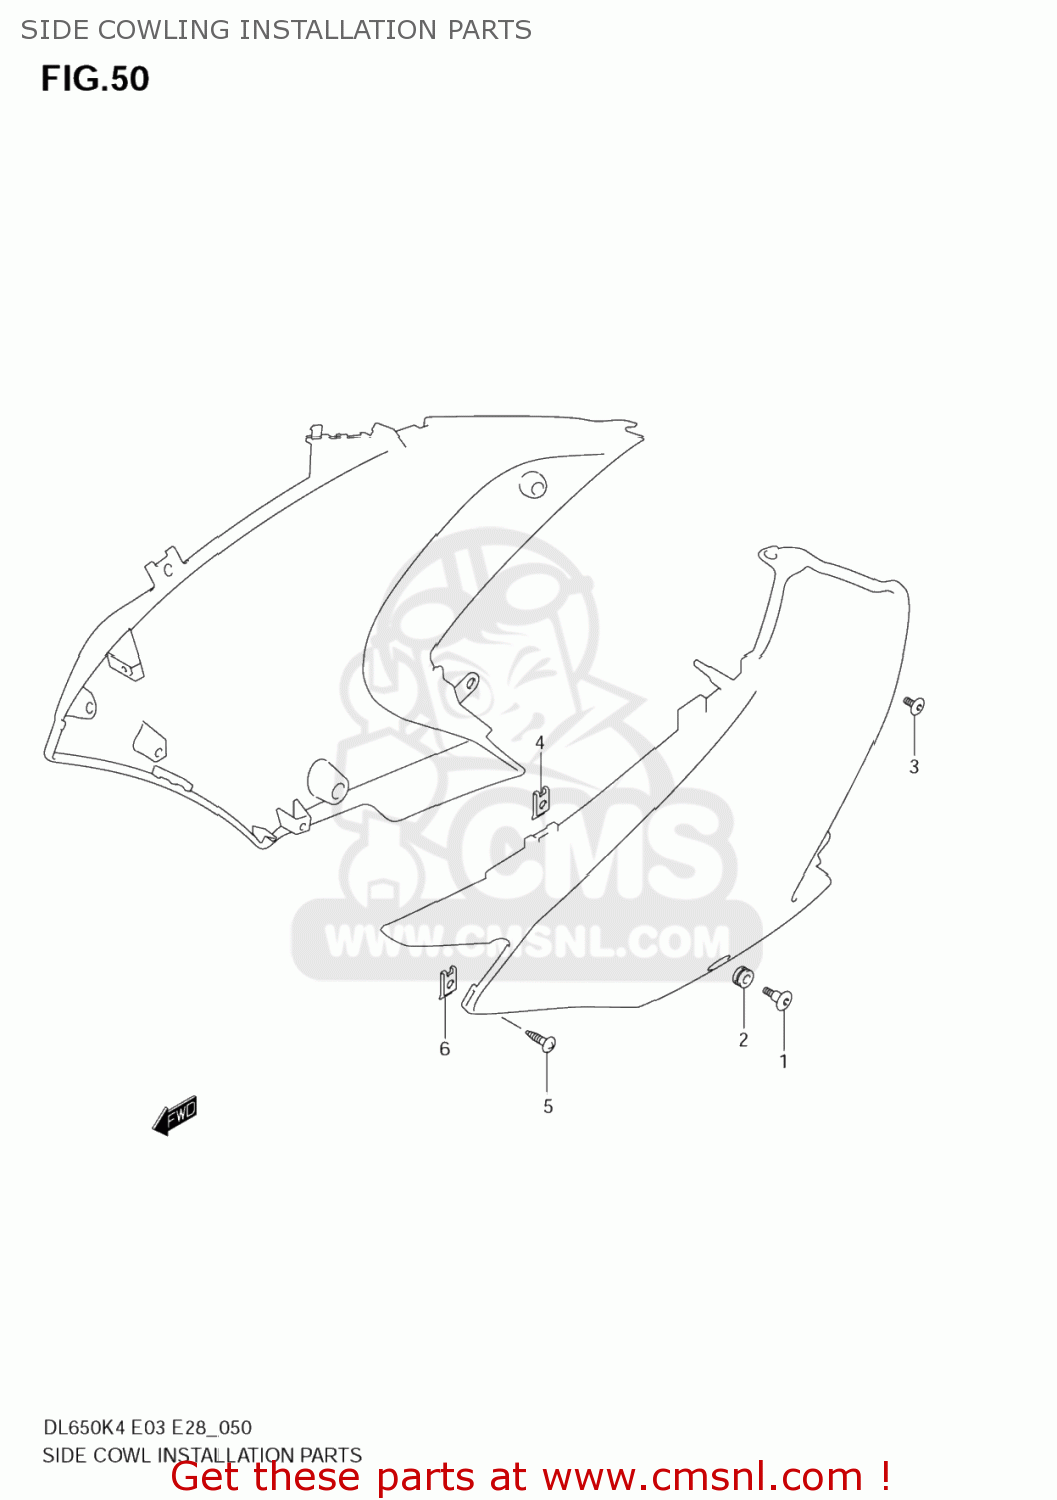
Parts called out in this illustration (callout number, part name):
1	SCREW(6X20)
2	CUSHION
3	SCREW(6X10)
4	NUT,COWL
5	SCREW
6	NUT
